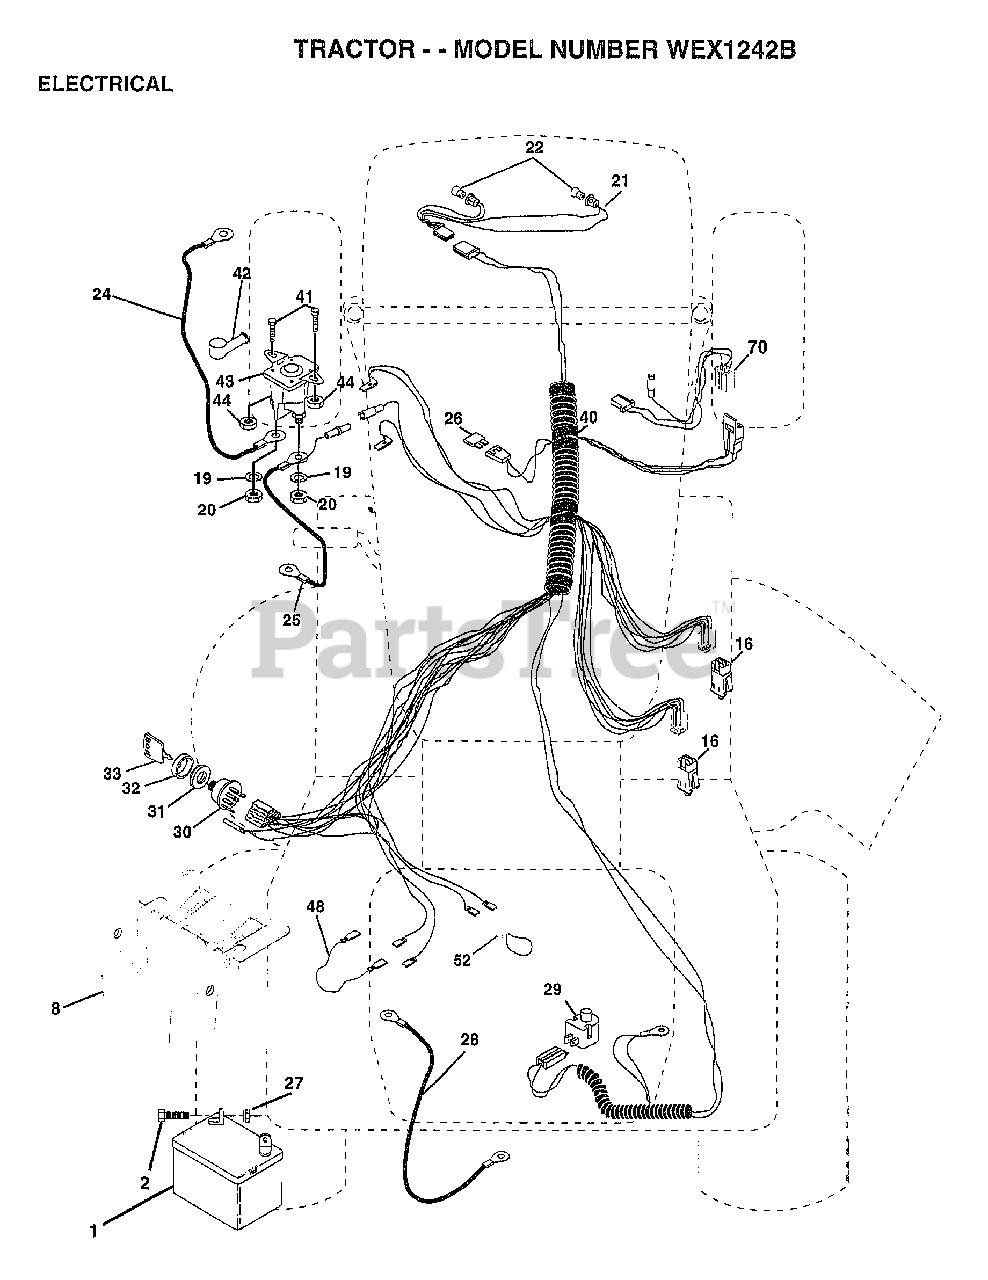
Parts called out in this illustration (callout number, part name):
2	BOLT LT
8	"CASE,BATTERY.MECH"
16	SWITCH INTERLOCK
20	NUT
21	HARNESS.ASM.LIGHT W/4152J
22	HEADLAMP BULB
24	"CABLE T, BATTERY"
25	CABLE.BTRY.6GA.RD
26	FUSE.15 AMP
27	NUT
28	CABLE T
29	SWITCH SEAT
30	SWITCH IGN 4POS
31	NUT IGNITION
32	COVER KEY SWITCH
33	KEY
40	HARNESS.IGNITION
41	BOLT HXHD FIN
44	NUT HXKEP 1/4X20
48	ADAPTER AMMETER
52	PROTECTION LOOP
70	HARNESS.ENGINE
